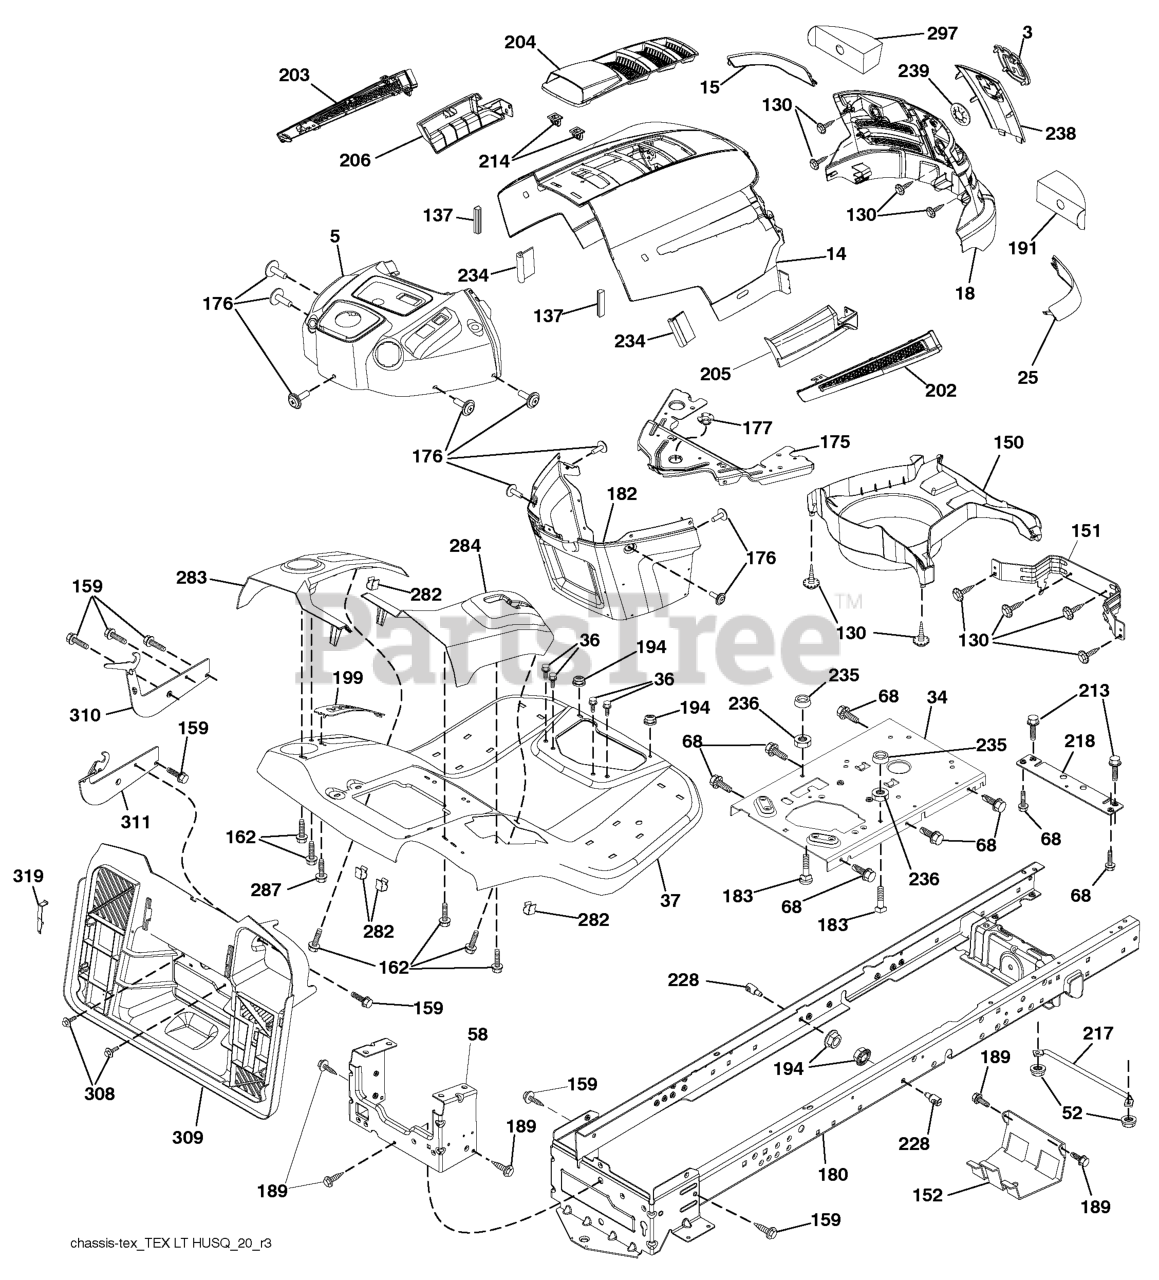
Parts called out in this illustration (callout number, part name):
3	RP LOGO
5	DASH
14	HOOD
15	LENS.HUSQVARNA LT.LH
18	GRILLE.SVC.HUSQVARNA.LT.GREY
25	LENS.HUSQVARNA LT.RH
34	PLATE.ENGINE.WELDED.CHASSIS
36	SCREW 5/16"
37	FENDER.PNT.SRD.30R
52	LOCKNUT
58	DRAWBAR UPPER 2PC SMALL FENDER
68	Screw Thdrol. 5/16-18 x 1/2
130	SCREW.#10 X 0.750.BOS
137	BUMPER DASH
151	BRACKET PIVOT
152	SHIELD.BROWNING.W/TEX
159	SCREW, 3/8-16X3/4
162	SCREW.HI-LO.CONSOLE
175	CROSSMEMBER
176	SCREW.#10-24X5/8.RN.QU
177	BUSHING STEERING
180	CHASSIS.WLDMNT.14GA.2PC.18".TI
182	DASH.LOWER.PREDATOR LT
183	BOLT.5/16-18X1-1/4 FULL.THREAD
189	SCREW
191	INSERT.REFLECTIVE.RH.
194	NUT LOCK HEX FLANGE 5/16-18
199	PLATE DECK LIFT
202	VENT SIDE HOOD RH
203	VENT SIDE HOOD LH
204	VENT TOP HOOD
205	SKIRT SIDE RH
206	SKIRT SIDE LH
213	BOLT
214	CLIP.RETAINER.TINNER.
217	ROD.PIVOT.HOOD
218	X-PIECE.HOOD.STOP.NON/
228	STUD.FASTNER.W/ANTI-ROTATE
234	BUMPER.HOOD.TEX.HUSQVARNA
235	SPACER FENDER
236	NUT.CENTERLOCK.5/16-
238	TRIM
282	CLIP.RETAINER.CONSOLE.LT.HUSQ
283	CONSOLE.DCKLFT.SRD.BGR
284	CONSOLE.SHFT.SRD.RH.GR
287	SCREW 1/4X20
297	INSERT REFLECTIVE
308	BOLT.5/16-18UNCX3/4 W/SEMS.BLK
309	BACKPLATE.BAGGER.V2.SRD
310	Bracket Hangar Bag LH
311	Bracket Hangar Bag RH
319	BRACKET.ACTUATOR.BAGGER.SRD
